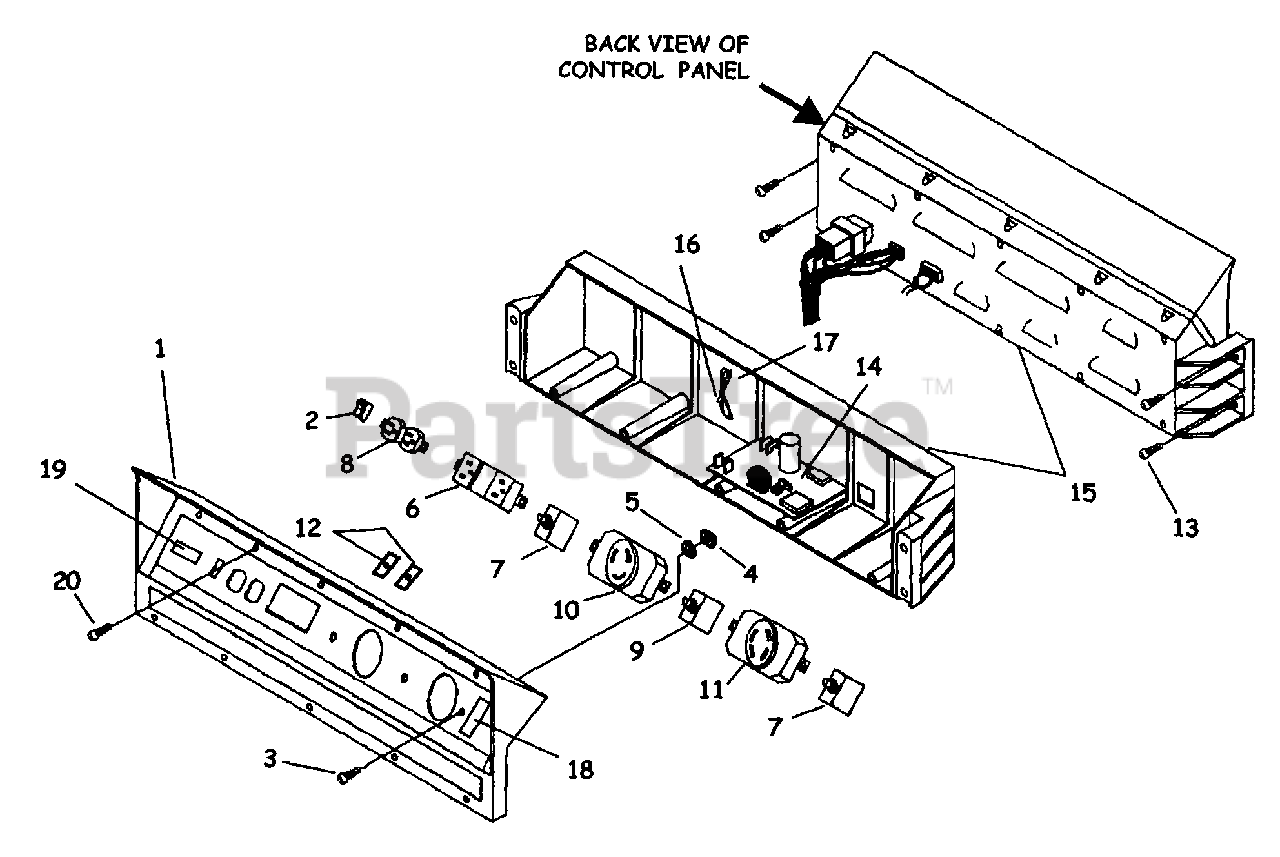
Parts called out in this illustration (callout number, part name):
1	Control Panel
2	Switch
3	Screw - Pan Hd. (8-32 X 7/8")
4	Nut - Hex
5	Washer - Lock
6	Receptacle (GFCI)
7	Circuit Breaker (20 amp)
8	Receptacle - Duplex
9	Circuit Breaker (30 amp)
10	Receptacle - Locking (120V)
11	Receptacle - Locking (240V)
12	Rubber Bumper
13	Screw - Torx Hd. (10-24 X 1/2")
14	Control Board
15	Control Panel Back
16	Clip, Tie
17	Tie, Cable
18	Volt Meter
19	Hour Meter
20	Screw, Plastite (8-16 X 3/4")
